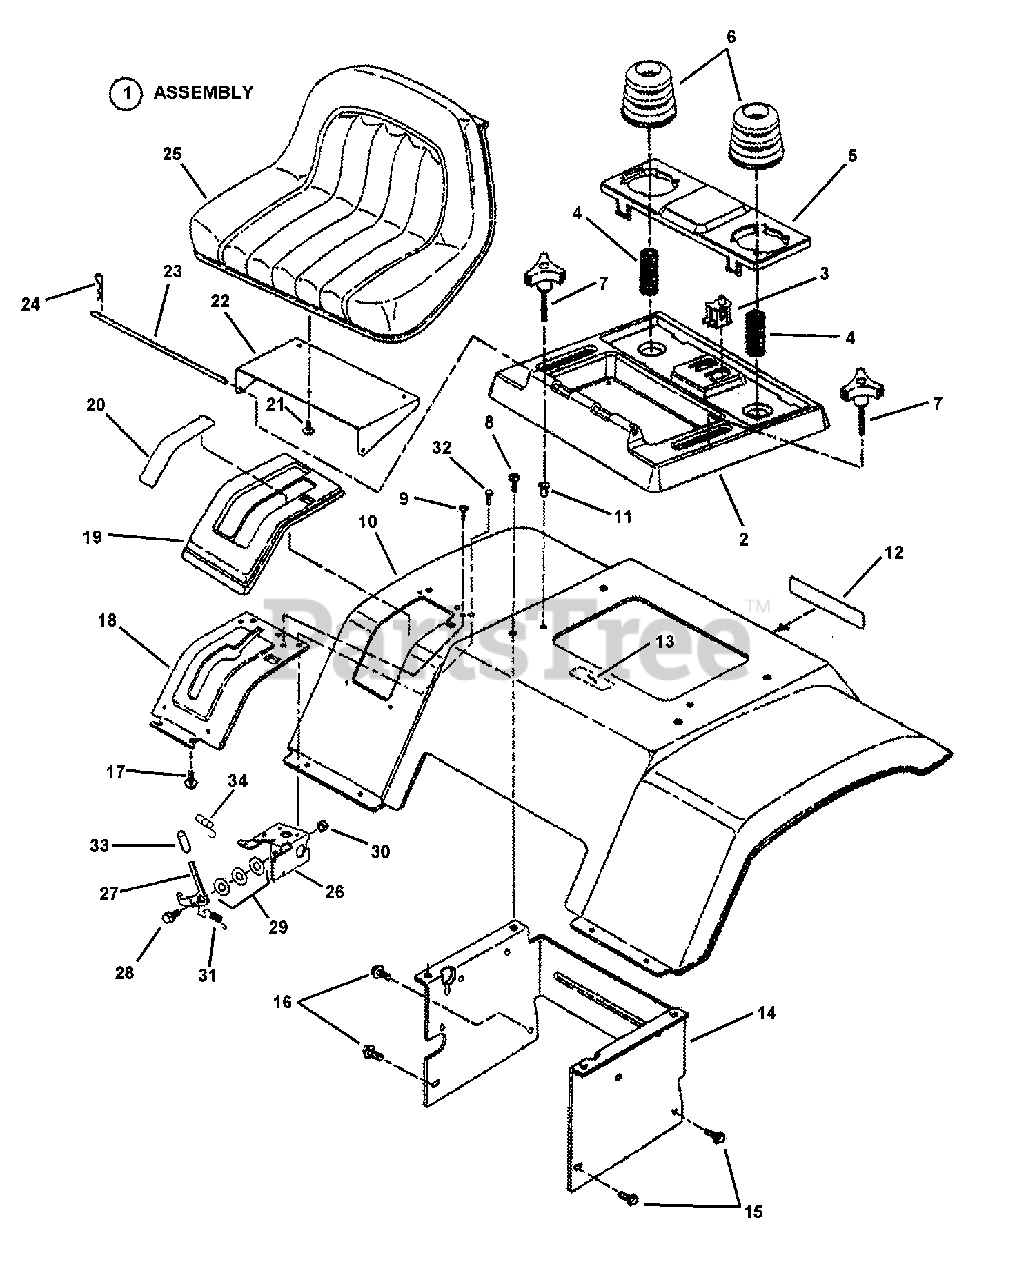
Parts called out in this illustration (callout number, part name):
1	ASSEMBLY, Seat Support
1	ASS'Y, Seat Support (Incl. items 2A, 3, 4 & 5)
2	SUPPORT, Seat
2A	SUPPORT, Seat- Electric Clutch
3	SWITCH, Seat, Gray (NC)
4	SPRING, Cushion Holder
5	HOLDER, Seat Cushion Electric Clutch
6	SPRING COVER, Rubber
7	KNOB, 3 Prong 5/16-18 x 2" Stud
8	SCREW, 5/16-18 x 5/8" Truss Head (Torx)
9	SCREW, 1/4-20 x 5/8" Hex Washer Self-Tap
10	SEAT PAN, Tractor- "No Mow in Reverse" Fender
11	RIV-NUT, 5/16-18 Round
12	DECAL, Snapper- Hood- 3D, Silver Letters
13	DECAL, Caution-Battery Installation, Fender
14	SUPPORT, Fender, Electric Clutch-K 46
15	SCREW, 5/16-18 x 5/8" Hex Washer Head
16	SCREW, 5/16-18 x 1-1/4" Swage
17	SCREW, #10-16 x 1/2 HXWA
18	QUADRANT- Shift- No Mow in Reverse
19	COVER, Shift (Black)
20	DECAL, Shift Cover, 5-Speed
20	DECAL, Shift Cove, 5-Speed
21	BOLT, 5/16-18 x 1" Hex Flange Lock
22	SUPPORT, Seat, Upper
23	ROD, Seat Hinge
24	HAIR PIN, 3/32 x 1.5"
25	SEAT, Operator (V1400)
25	SEAT, Operator (Milsco XB110)
26	ASSEMBLY, Stop Latch- Lock Out
27	LATCH, Overide-No Mow in Reverse
28	SHOULDER BOLT, 5/16-18
29	SHIM-WASHER
30	NUT, 5/16-18-3B Hex Nyloc
31	SPRING, Extension- Manual No Mow
32	SCREW, #10-24 x 1/2" Hex Washer Self-Tap (Torx)
33	CAP - Vinyl
34	SPRING, Extension, Latch Return
